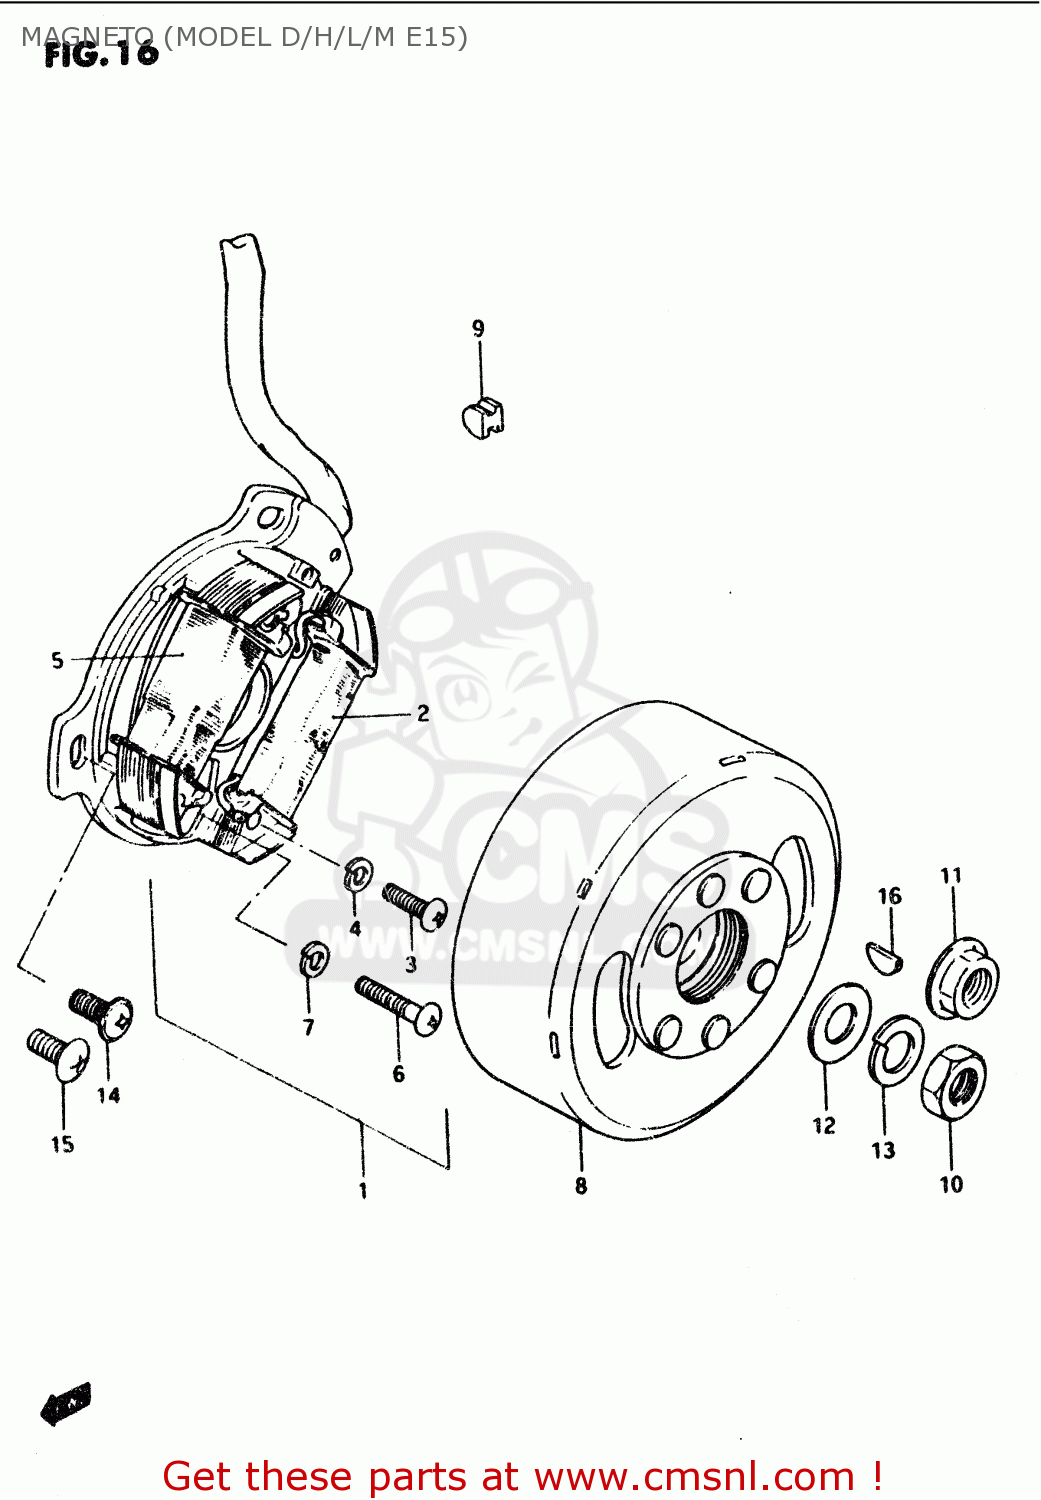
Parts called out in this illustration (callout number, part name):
1	STATOR ASSY
2	COIL,PRIMARY
3	SCREW
4	WASHER,LOCK 4M
5	COIL, LIGHTING
6	SCREW 4X25
7	WASHER,LOCK 4M
8	ROTOR ASSY
9	PLUG
10	NUT (10MM)
11	NUT
12	WASHER
13	WASHER,LOCK,10
14	SCREW(5X14)
15	SCREW
16	KEY
